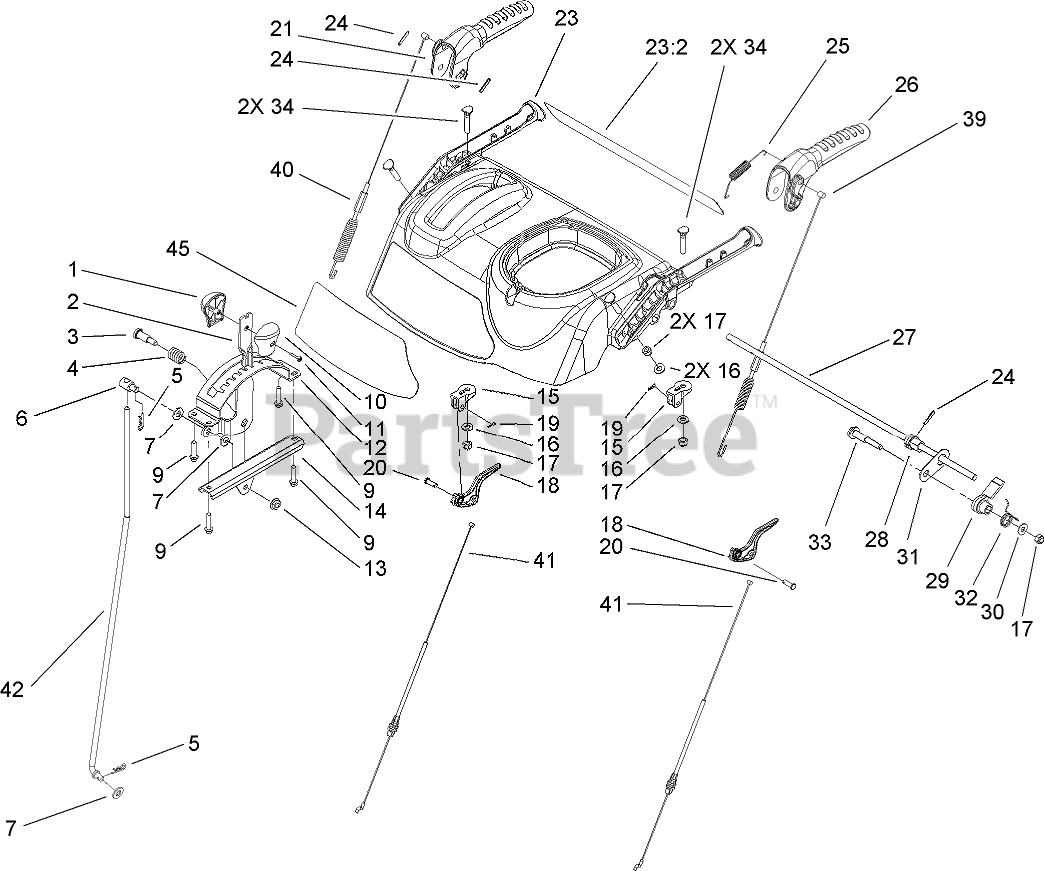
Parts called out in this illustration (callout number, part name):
1	KNOB-SHIFT, RH
2	SELECTOR-SPEED
3	SCREW-SHOULDER
4	SPRING-COMPRESSION
5	PIN-COTTER
6	TRUNNION-ROD
7	WASHER-FLAT
9	SCREW-PLASTITE
10	KNOB-SHIFT, LH
11	SCREW-PPH
12	GUIDE-SELECTOR, SPEED
13	NUT-HF
14	MOUNT-SELECTOR, SPEED
15	MOUNT-CLUTCH, LEVER
16	WASHER-FLAT
17	NUT-LOCK, NI
18	LEVER-CLUTCH
19	PIN-HAIR
20	PIN-CLEVIS
21	LEVER-AUGER
23	PANEL-CONTROL
23:2	DECAL-WARNING
24	PIN-SPRING
25	SPRING-TENSION
26	LEVER-TRACTION
27	ROD-LOCKOUT
28	CAM-LOCKOUT
29	LATCH-LOCKOUT
30	WASHER-FLAT
31	LINK-LOCKOUT
32	SPRING-TORSION
33	SCREW-SHOULDER
34	SCREW-HANDLE
39	CABLE-TRACTION
40	CABLE-AUGER
41	CABLE-CLUTCH
42	ROD-SHIFT
45	DECAL-CONTROL PANEL
